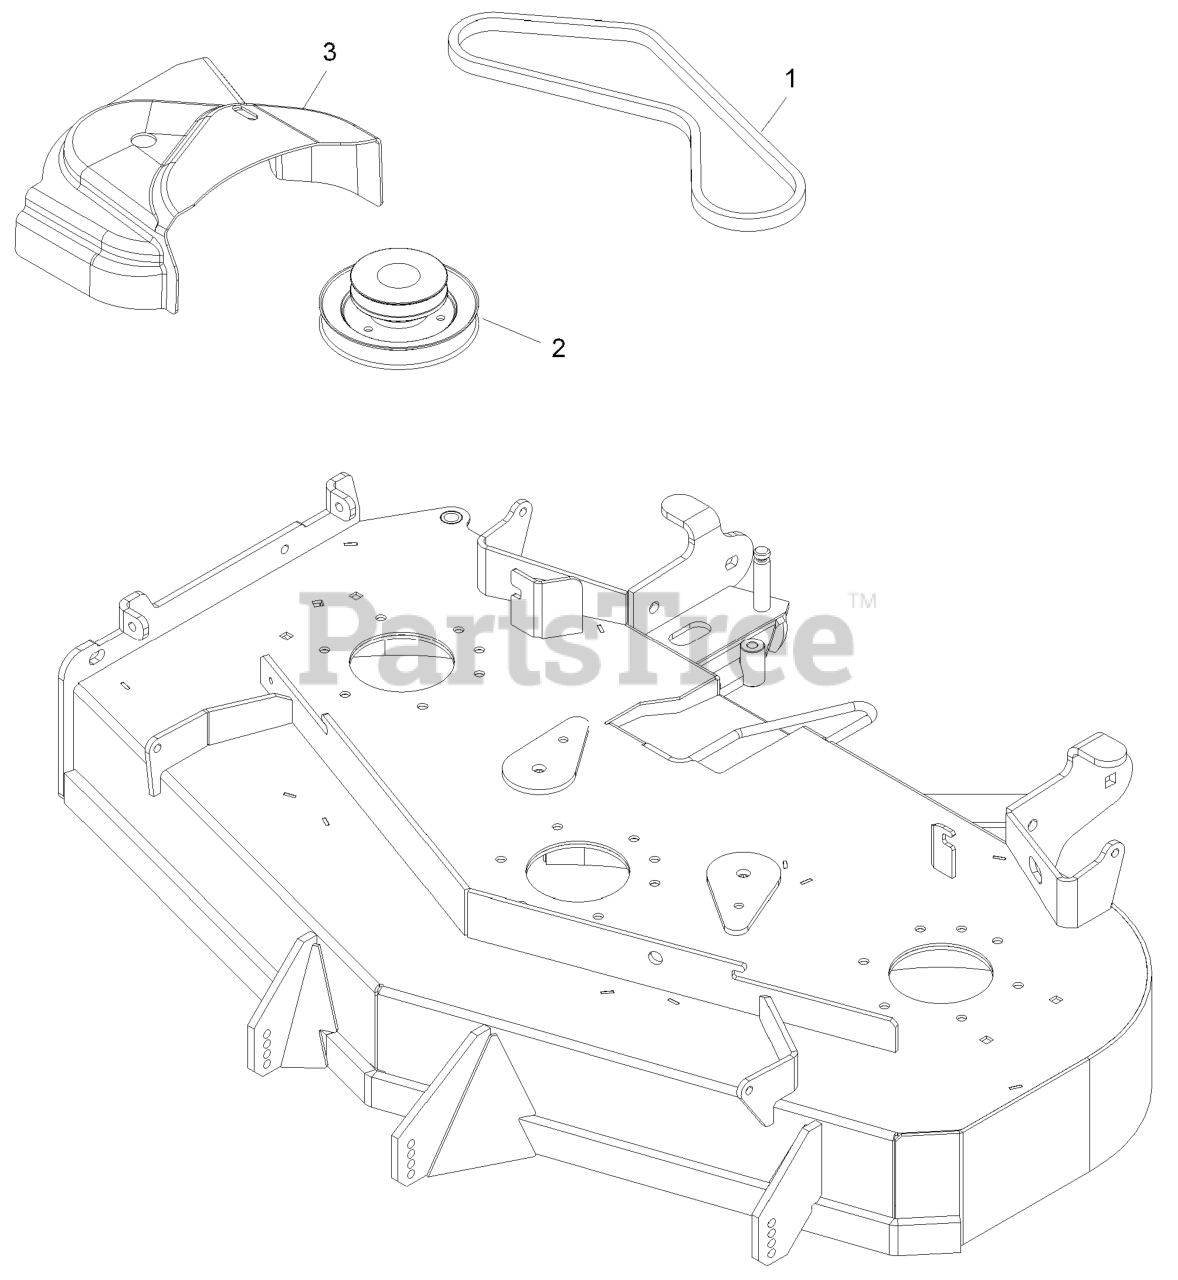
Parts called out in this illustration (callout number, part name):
1	Belt, Blower (48")
2	Jackshaft,Uv Drive 484
3	Cover,Belt Uv 48
